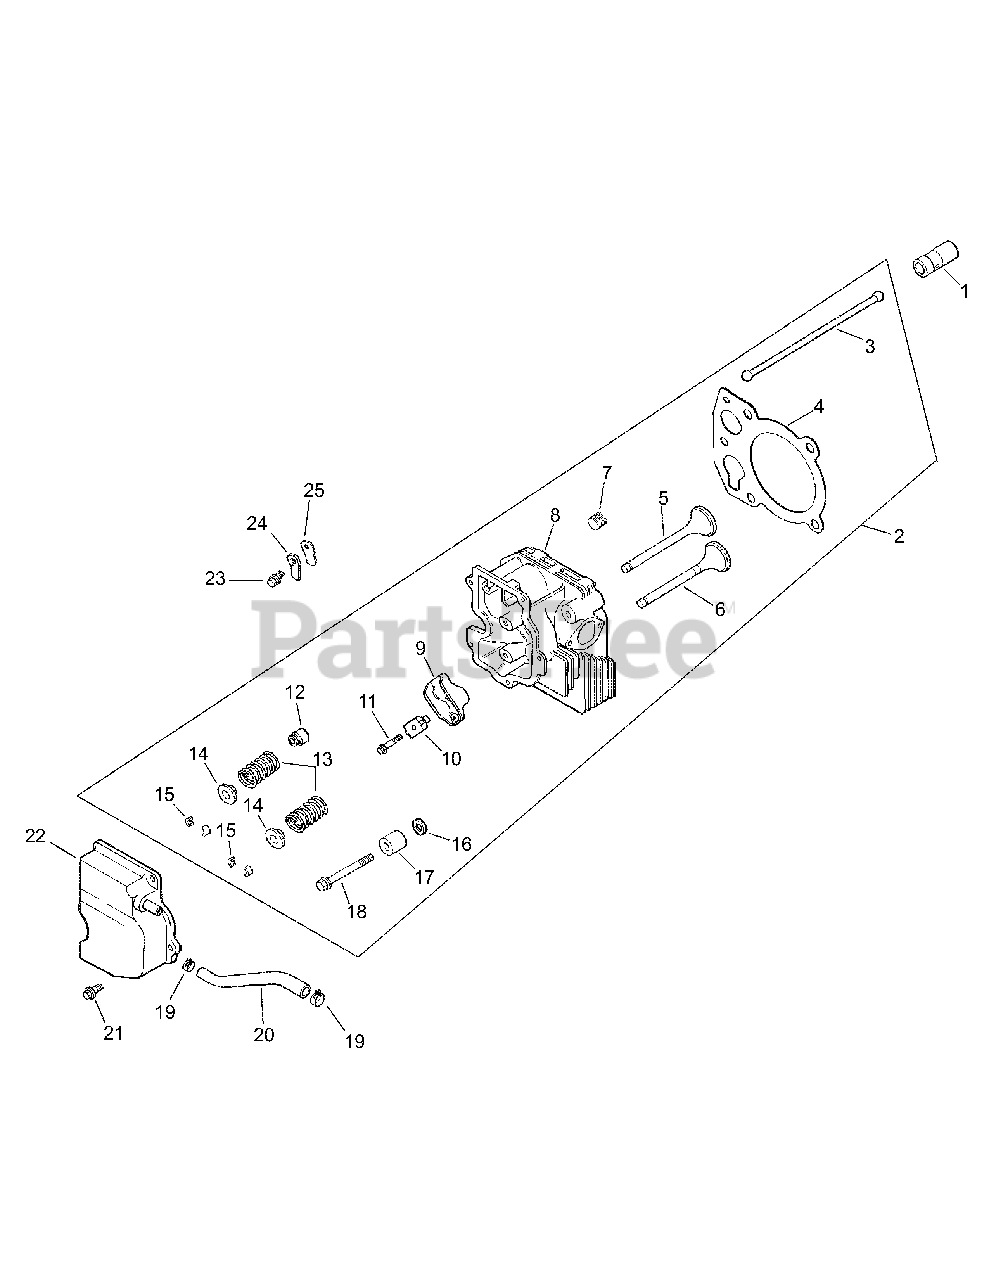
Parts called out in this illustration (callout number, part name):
1	Lifter, Valve
2	Kit, Cylinder Head
3	Rod, Push
4	Gasket, Cylinder Head
5	Valve, Intake (Std.)
6	Valve, Exhaust (Std.)
7	Plug, Allen Hd. 1/8" Pipe
8	Cylinder Head
10	Pivot, Rocker Arm
11	Screw, Hex. Flange M6 x 1.0 x 34
12	Seal, Valve Stem
13	Spring, Valve
14	Cap, Valve Spring
15	Kit, Retainer
16	Washer, Plain 13/32"
17	Spacer, Head Bolt Exhaust Port
18	Screw, Hex. Flange M10 x 1.5 x 81
19	Clamp, Hose
20	Hose, Breather
21	Screw, Hex. Flange M6 x 1.0 x 20
22	Cover, Valve W/nipple
23	Screw, Hex. Flange M5 x 0.8 x 10
24	Retainer, Breather Reed
25	Reed, Breather
